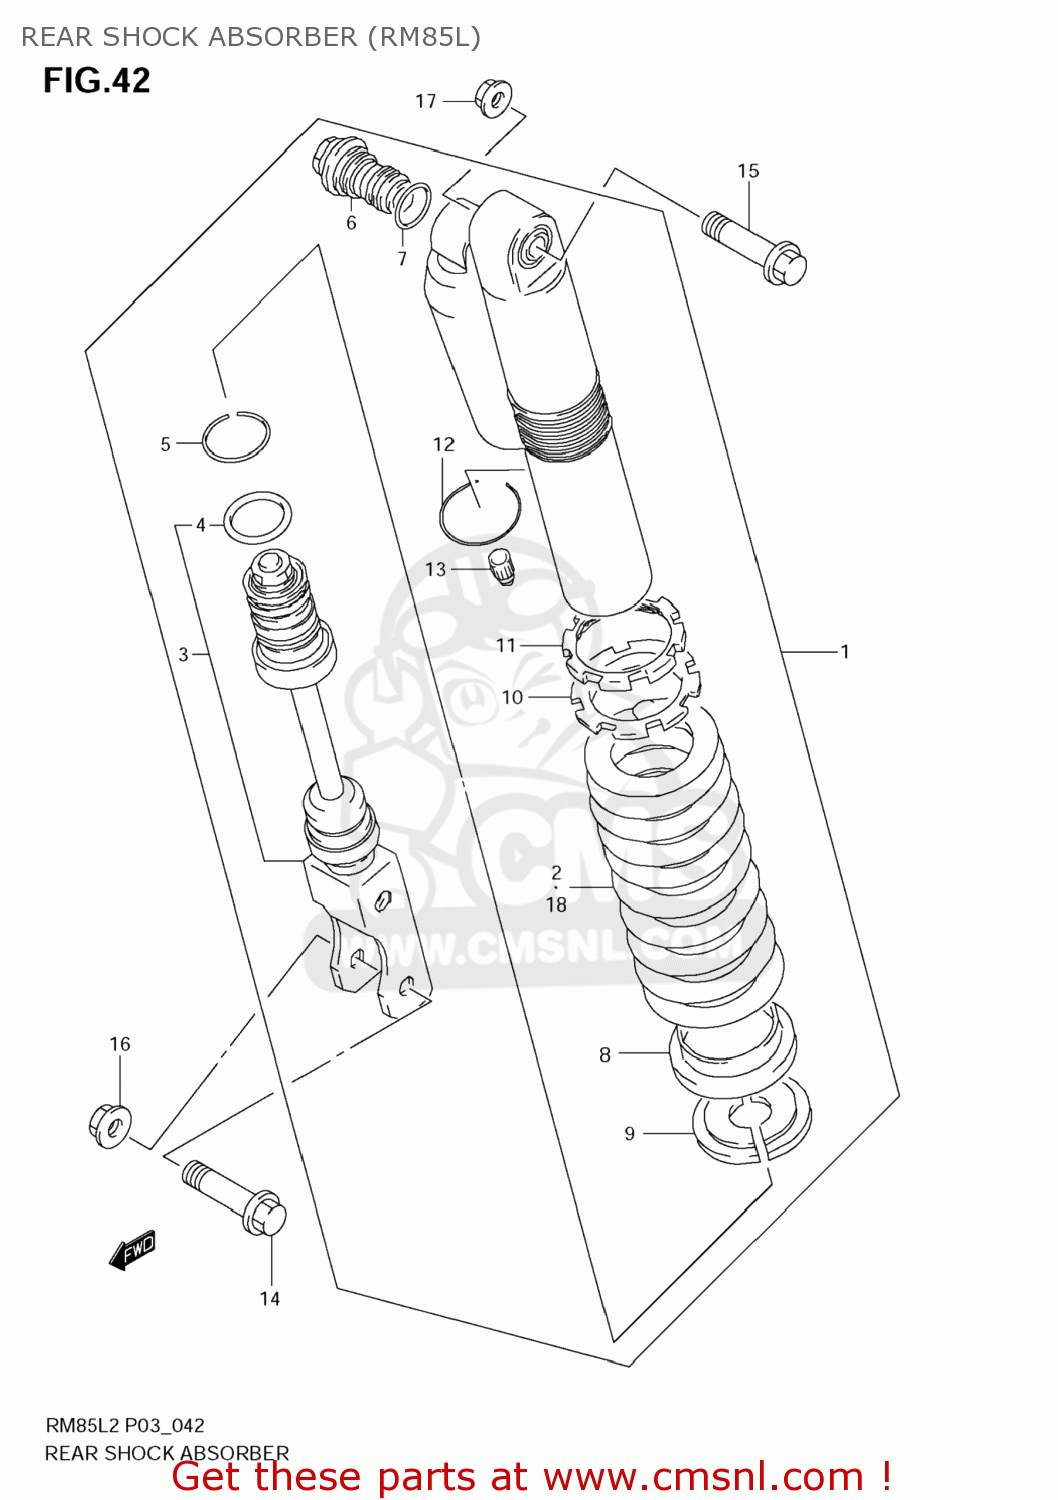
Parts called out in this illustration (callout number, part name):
1	ABSORBER ASSY,RR SHOCK
2	SPRING,RR(K=4.8)
3	ROD,PISTON
4	O RING
5	RING,STOPPER
6	BOLT,PLUG
7	O RING
8	SEAT,SPRING
9	SEAT,SPRING STOPPER
10	ADJUSTER,SPRING
11	NUT,SPRING ADJUSTER
12	RING,STOPPER
13	CAP
14	BOLT,RR SHOCK ABSORBER LWR
15	BOLT,RR CUSHION ROD UPR
16	NUT
17	NUT
18	SPRING,RR(K=4.6)
